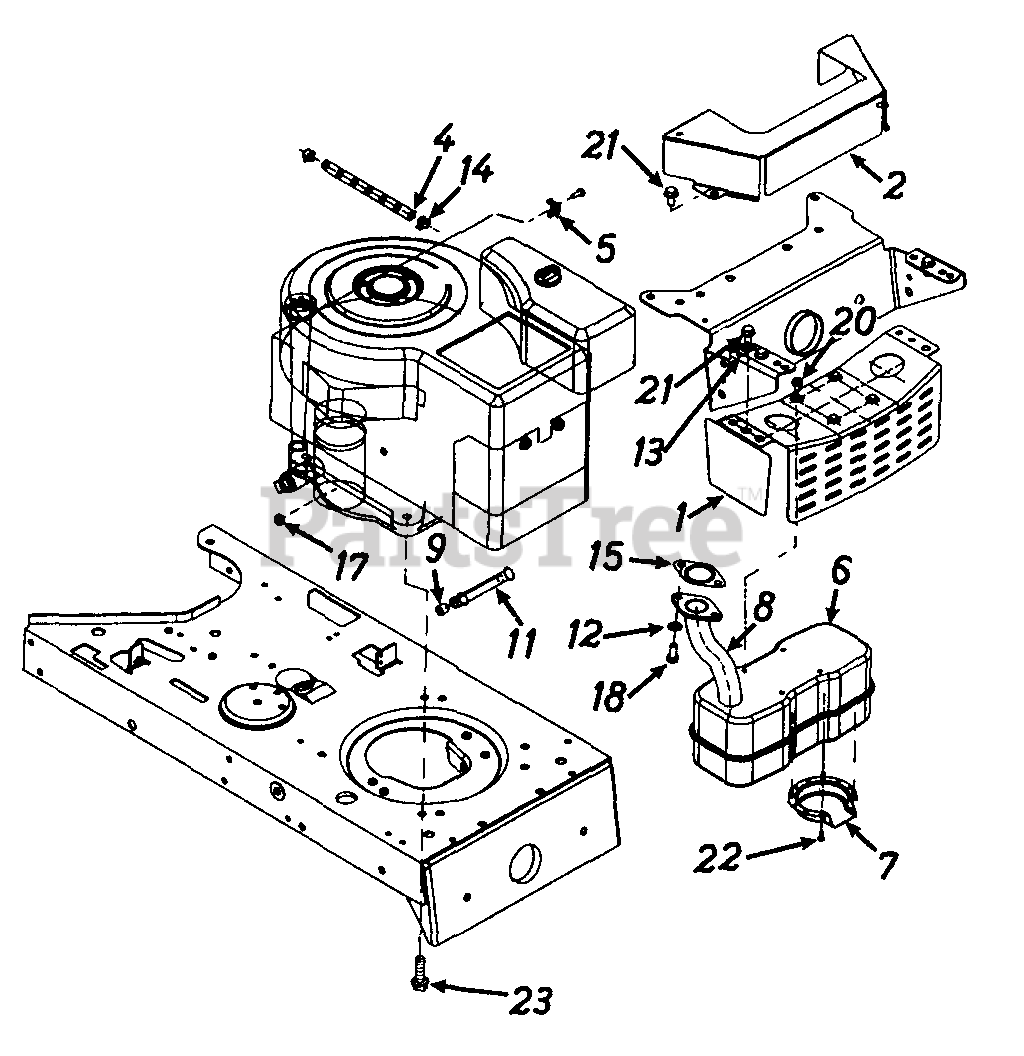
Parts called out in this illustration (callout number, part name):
1	Heat Shield Bracket
4	Fuel Line
5	Casing Clamp
6	Muffler
7	Muffler Deflector
8	Exhaust Pipe
9	Hex Pipe Plug
11	Pipe 3/8 NPT x 3.8" Lg.
12	L-Wash. 5/16" I.D.
13	Clamp
14	Hose Clamp
15	Exhaust Gasket
17	Hex Sems Nut 1/4-20 Thd
18	Socket Hd. Bolt 5/16-18 x .62" Lg.
20	Hex Wash Hd. TT-Scr 1/4-20 x .5" Lg.
21	Hex Wash Hd. TT-Scr 5/16-18 x .62" Lg.
22	Hex Bolt #8-32 x .38" Lg
23	Hex Wash Hd. TT-Scr 3/8-16 x 1.25" Lg.
